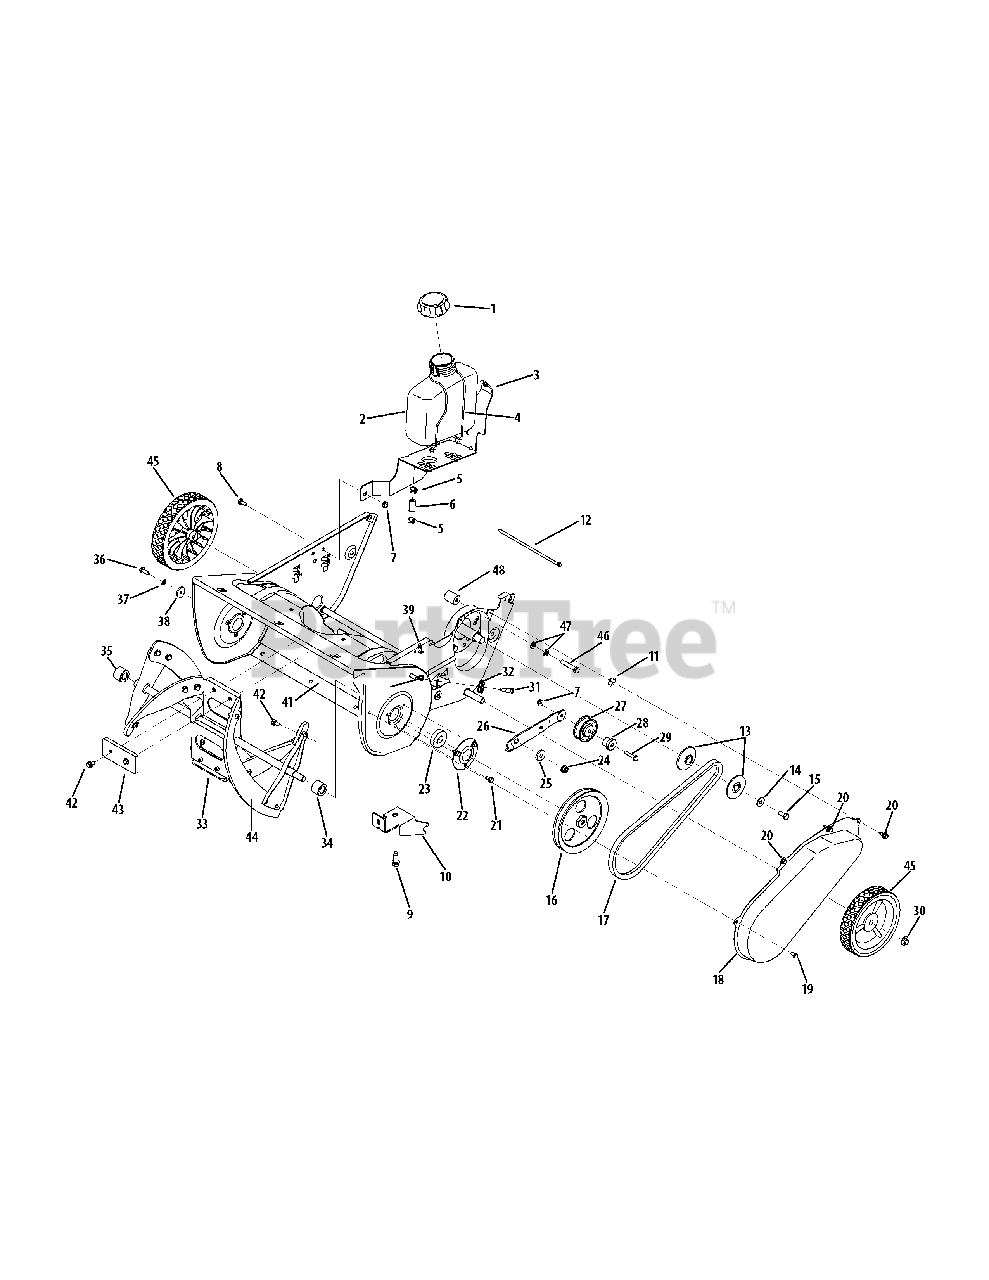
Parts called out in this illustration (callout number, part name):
1	Cap-Fuel
2	Fuel Tank 2 Quart
3	Gas Tank Support Bracket
4	Gas Tank Wire Support
5	Hose Clamp
6	Fuel Line
7	Hex L-Flanged Nut 1/4-20 Gr. F Ny
8	Hex Bolt 1/4-20 x .62 Gr. 5
9	Hex Wash HD Tap Scr 3/8-16 x .88
10	Engine Bracket
11	Push Nut
12	Push Mount Tie
13	Pulley Half .625 ID x 2.25 OD
14	Flat Washer .340 ID x .872 OD x .060
15	Hex L-Bolt 5/16-24 x .75 Gr. 5
16	Pulley 1/2 x 6,0" OD
17	V-Belt 1/2 x 35.0" Lg.
18	Belt Cover
19	Hex Wash HD Tapp Scr 1/4-20 x .375
20	Hex B-Tap Scr 1/4-28 x .25" Lg
21	Hex Tap Scr. 1/4-14 x .5" Lg.
22	Bearing Cup
23	Ball Bearing .625 x 37 x 12.63
24	Flange Locknut 5/16-18 Gr. F, Nylon
25	Shoulder Spacer .25 THK
26	Idler Bracket
27	Idler Pulley Ass'y
28	Shld. Spacer .260 x .785 x .538
29	Hex Screw 1/4-20 x 1.25 Gr. 5 Spe cial
30	Push Cap x 1/2" Rod
31	Hex Shld.Scr.1/4-28 x .375
32	Cable Guide Roller
33	Auger Assembly
34	Auger Spacer LH
35	Auger Spacer RH
36	Thd Forming Scr. 1/4-20 x .75 Lg.
37	L-Wash 1/4 ID
38	Flat Washer .25 ID x .93 OD x .125
39	Extension Spring .33 x 1.12
40	Hex Ins Jam L-Nut 1/4-28
41	Auger Assembly Housing
42	Hex Wash. Hd. TT Scr. 1/4-14 x .625
43	Rubber Paddle
44	Rubber Spiral-Crescent
45	Wheel, 7.0 x 1.6 Diamond (White)
46	Hex Bolt 5/16-24 x 1.75
47	L-Wash 5/16 ID
48	Spacer .875 x .320 x 1.10
